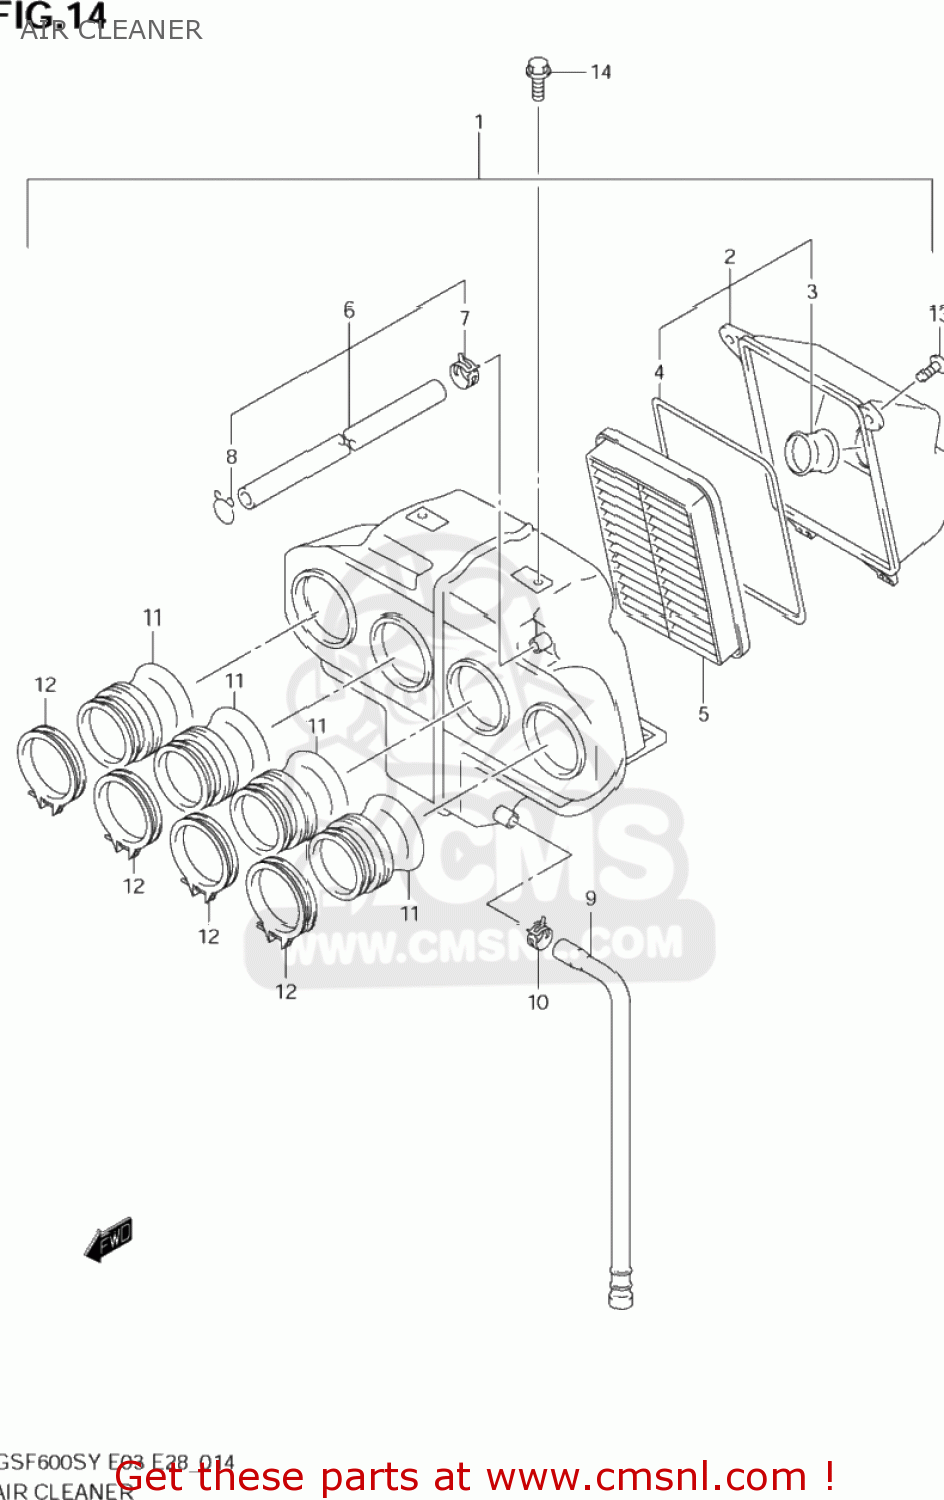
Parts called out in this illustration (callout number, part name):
1	CLEANER ASSY,AIR
2	CAP,AIR CLEANER
3	TUBE,INLET
4	GASKET,AIR CLEANER CAP (NAS)
5	FILTER,AIR
6	TUBE,BREATHER
7	CLIP
8	CLIP
9	TUBE,DRAIN
10	CLIP
11	TUBE,OUTLET
12	CLAMP
13	SCREW 5X12
14	BOLT
